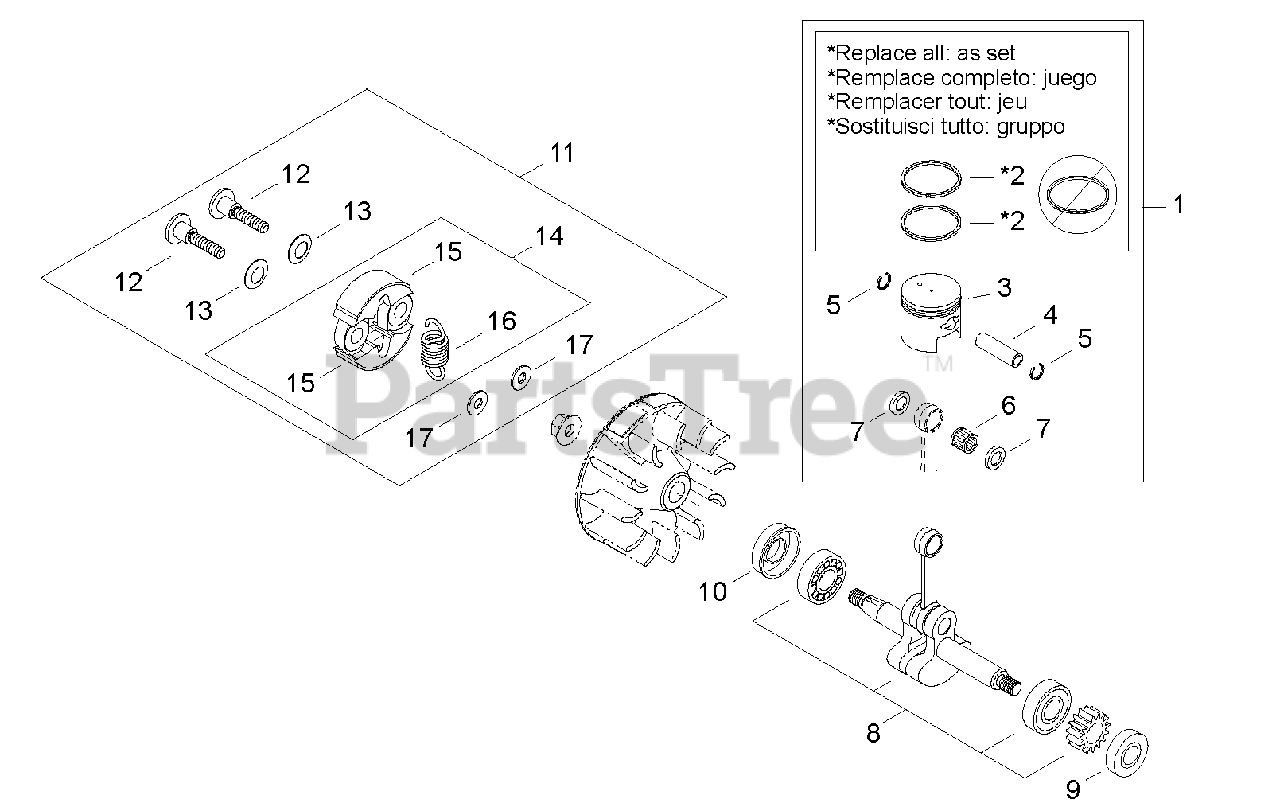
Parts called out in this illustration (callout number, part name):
1	PISTON KIT
2	RING, PISTON
3	PISTON
4	PIN, PISTON
5	RING, SNAP
6	BEARING, NEEDLE 9
7	WASHER, THRUST 9
8	CRANKSHAFT ASSY
9	SEAL, OIL 12
10	SEAL, OIL 12
11	CLUTCH ASSY
12	BOLT, CLUTCH
13	WASHER, SPRING
14	SHOE ASSY, CLUTCH
15	SHOE, CLUTCH
16	SPRING, CLUTCH
17	WASHER 6 MM
